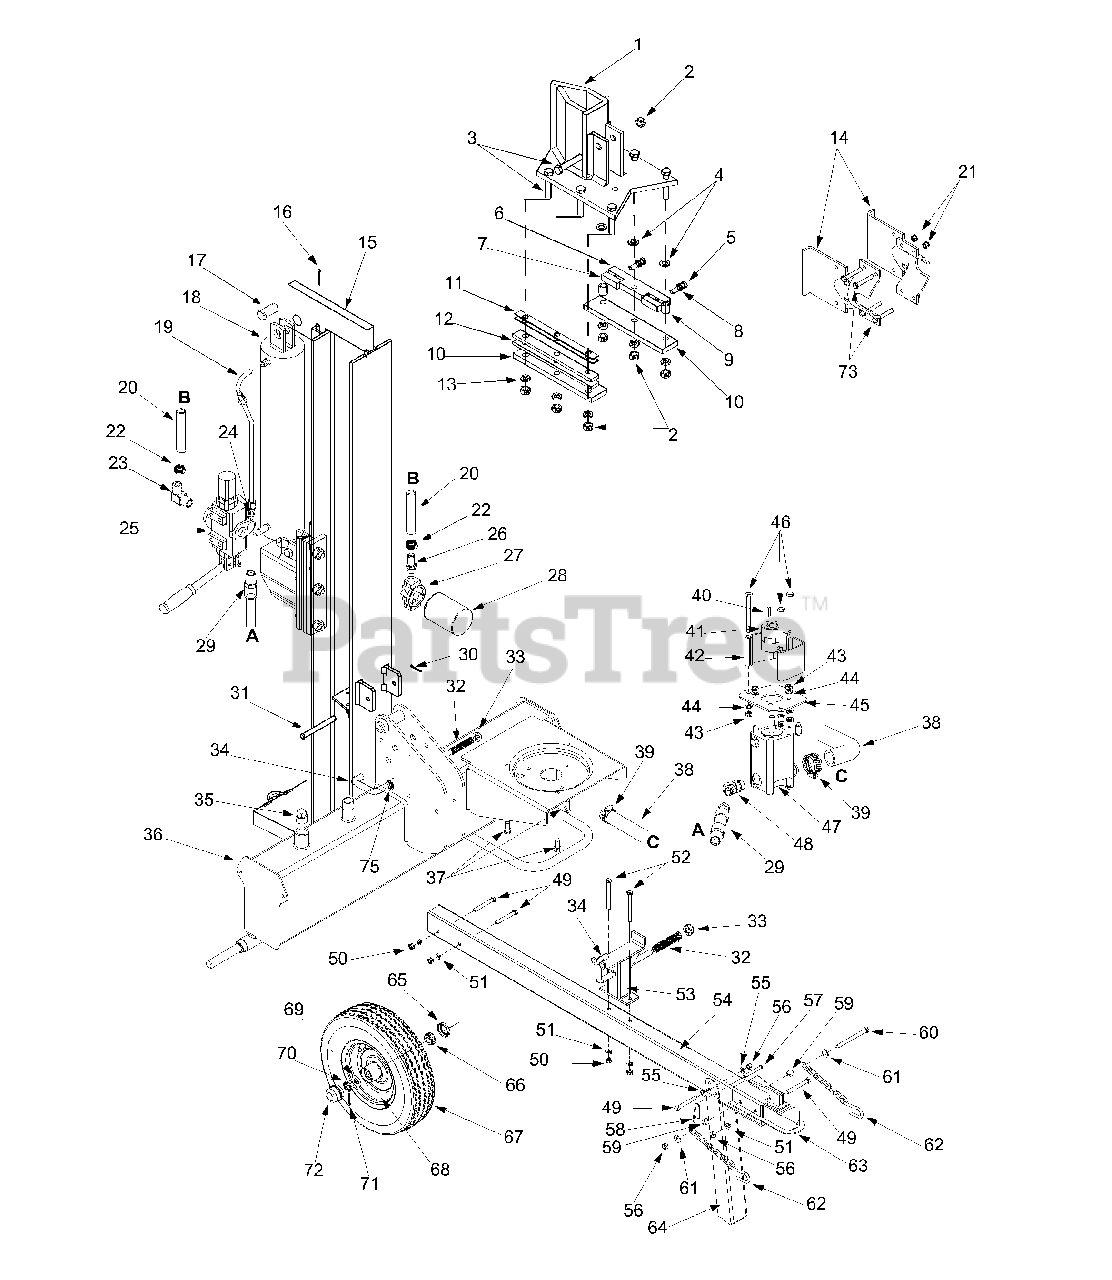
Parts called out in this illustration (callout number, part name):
2	Lock Nut 1/2-20
3	Hex Cap Screw 1/2-20 x 2.75
4	Flat Washer .531 x .93 x .090
5	Hex Cap Screw 3/8-24 x 1.5
8	Hex Jam Nut 3/8-24
9	Spacer
13	Lock Washer 1/2
17	Clevis Pin
19	Hydraulic Tube
20	Return Hose 3/4" I.D. x 44" Lg.
21	Lock Nut 3/8-16
22	Hose Clamp 5/8"
23	Return Elbow
24	90° Solid Male Adapter
26	3/4" Hose Adapter
27	Filter Housing
28	Oil Filter
29	High Pressure Hydraulic Hose
30	Cotter Pin 1/8" Dia.
31	Hinge Pin 1/2 x 4.8" Lg.
32	Comp. Spring 4" Lg.
33	Push Cap
34	Locking Rod
35	Pipe Plug
38	Suction Hose
39	Hose Clamp
40	Sq.-Key 3/16" x .75"
41	Flexible Coupling .750 x .500
41	Flexible Coupling .875 x .500
41	Flexible Coupling .875 x .437
42	Coupling Shield
43	Hex Nut 5/16-24
44	L-Wash. 5/16" I.D.
46	Hex Screw 5/16-24 x 3.25
47	Gear Pump (11 gpm)
47	Pump Kit
47	Gear Pump (9.5 gpm)
48	45 Degree Elbow
49	Hex Bolt 3/8-16 x 3" Lg.
50	Hex Nut 3/8-16 Thd.
51	L-Wash. 3/8" I.D.
52	Hex Bolt 3/8-16 x 4" Lg.
55	Flat Washer 3/8
56	Hex L-Nut 3/8-16 Thd.
57	Clevis Pin 5/16 x 2.5" Lg.
58	Spring Pin
59	Spacer 3/8" I.D. x .625" O.D.
60	Hex Bolt 3/8-16 x 4" Lg. (Grd 5)
61	Fl-Wash. 3/8" I.D. x .87" O.D.
62	Chain-Tow Hitch
63	Hitch Coupler
66	Bearing Cone
67	Wheel Assembly
68	Rim Assembly
69	Fl-Wash. .76" I.D. x 1.5" O.D.
70	Slotted Nut 3/4-16 Thd.
71	Cotter Pin 5/32" Dia. x 1-1/4" Lg.
72	Hub Cap
73	Hex Cap Screw 3/8-16 x 2.0
75	Flat Washer .635 ID x .93 OD
